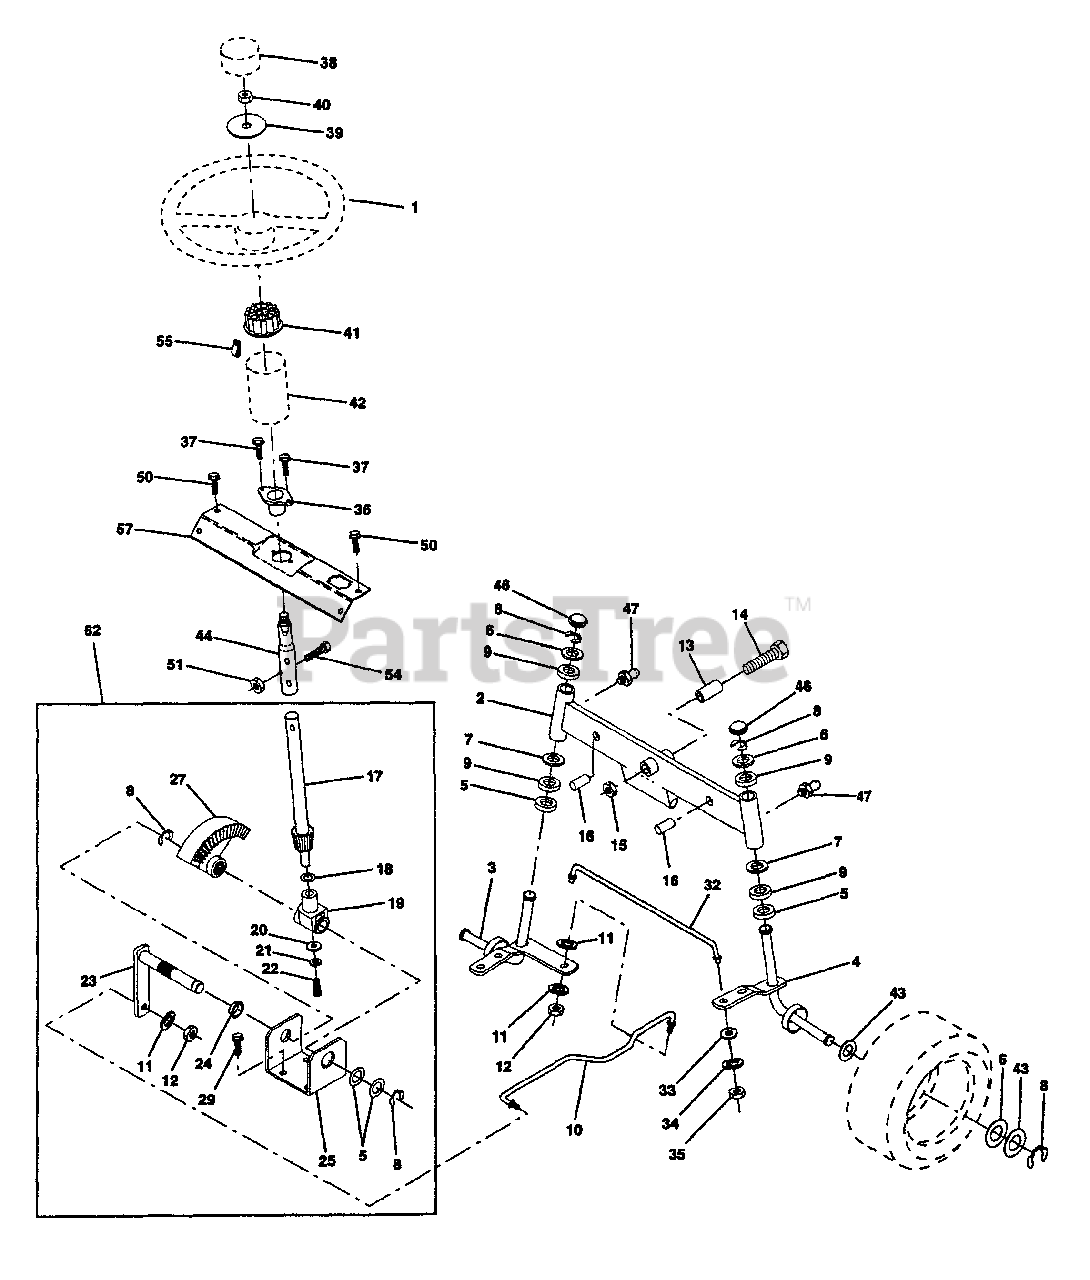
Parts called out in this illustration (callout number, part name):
1	Wheel Steering Auto Grey
2	Axle Asm Fr LT W/gzks 38/42
3	Spindle Asm LH
4	Spindle Asm RH
5	Bearing Race Thrust Harden
6	Washer 25/32 X 1-5/8 X 16 Ga
7	Washer 27/32 X 1-1/4 X 16 Ga
8	Ring Klip #t5304-75
9	Bearing Col Strg Blk
10	Link Drag Sol Ball Jt 20 064
11	Washer Lock Hvy Hlcl Spr 3/8
12	Nut Fin Hex 3/8-24 Unf
13	Spacer Bearing Axle Front
14	Bolt Hex 5/8-11 Unc X 3-1/2
15	Nut Lock Flange 5/8-11 Unc
16	Pin Axle 5/8 X 1 55/1 54 Lg
17	Shaft Asm Strg Private Label
18	Washer Thrust 515 x 750 x 033
19	Support Shaft
20	Washer Shim 1/4 X 5/8 X 062
21	Washer Lock Hvy Helical 1/4
22	Screw Hex Socket 1/4-20 X 5/8
23	Shaft Asm Pittman
24	Nyliner Snap In
25	Bracket Steering
27	Gear Sector
29	Screw Thdrol 3/8-16x3/4 Ty-tt
32	Rod Tie BJ Solid 19 75 Mech
33	Washer 11/32 x 3/4 x 16 Ga.
34	Washer Lock Hvy Hlcl Spr 5/16 Ga
35	Locknut 5/16-24 UNF
36	Bushing Strg
37	Screw Slftp #10-16 X 1/2 Ty-b
38	Insert Cap Strg Wh Au
39	Washer 13/32 X 2-3/8 X 8 Ga
40	Nut Lock Center 3/8-24unf
41	Adaptor Wheel Strg 640/ 635id
42	Boot Steering Shaft
43	Washer 25/32 X 1 1/4 X 16 Ga
44	Shaft Extention Steering
46	Cap Spindle Fr Top Blk
47	Fitting Grease
50	Screw Hex Wsh Thdrol 1/4-20 x 3/4
51	Nut Lock Hex w/Ins 5/16-18
54	Bolt Fin Hex 5/16-18 Unc x 1-1/4
55	Clip Tinnerman
57	Support Shaft Steering
62	Kit Steering, Asm. Service
